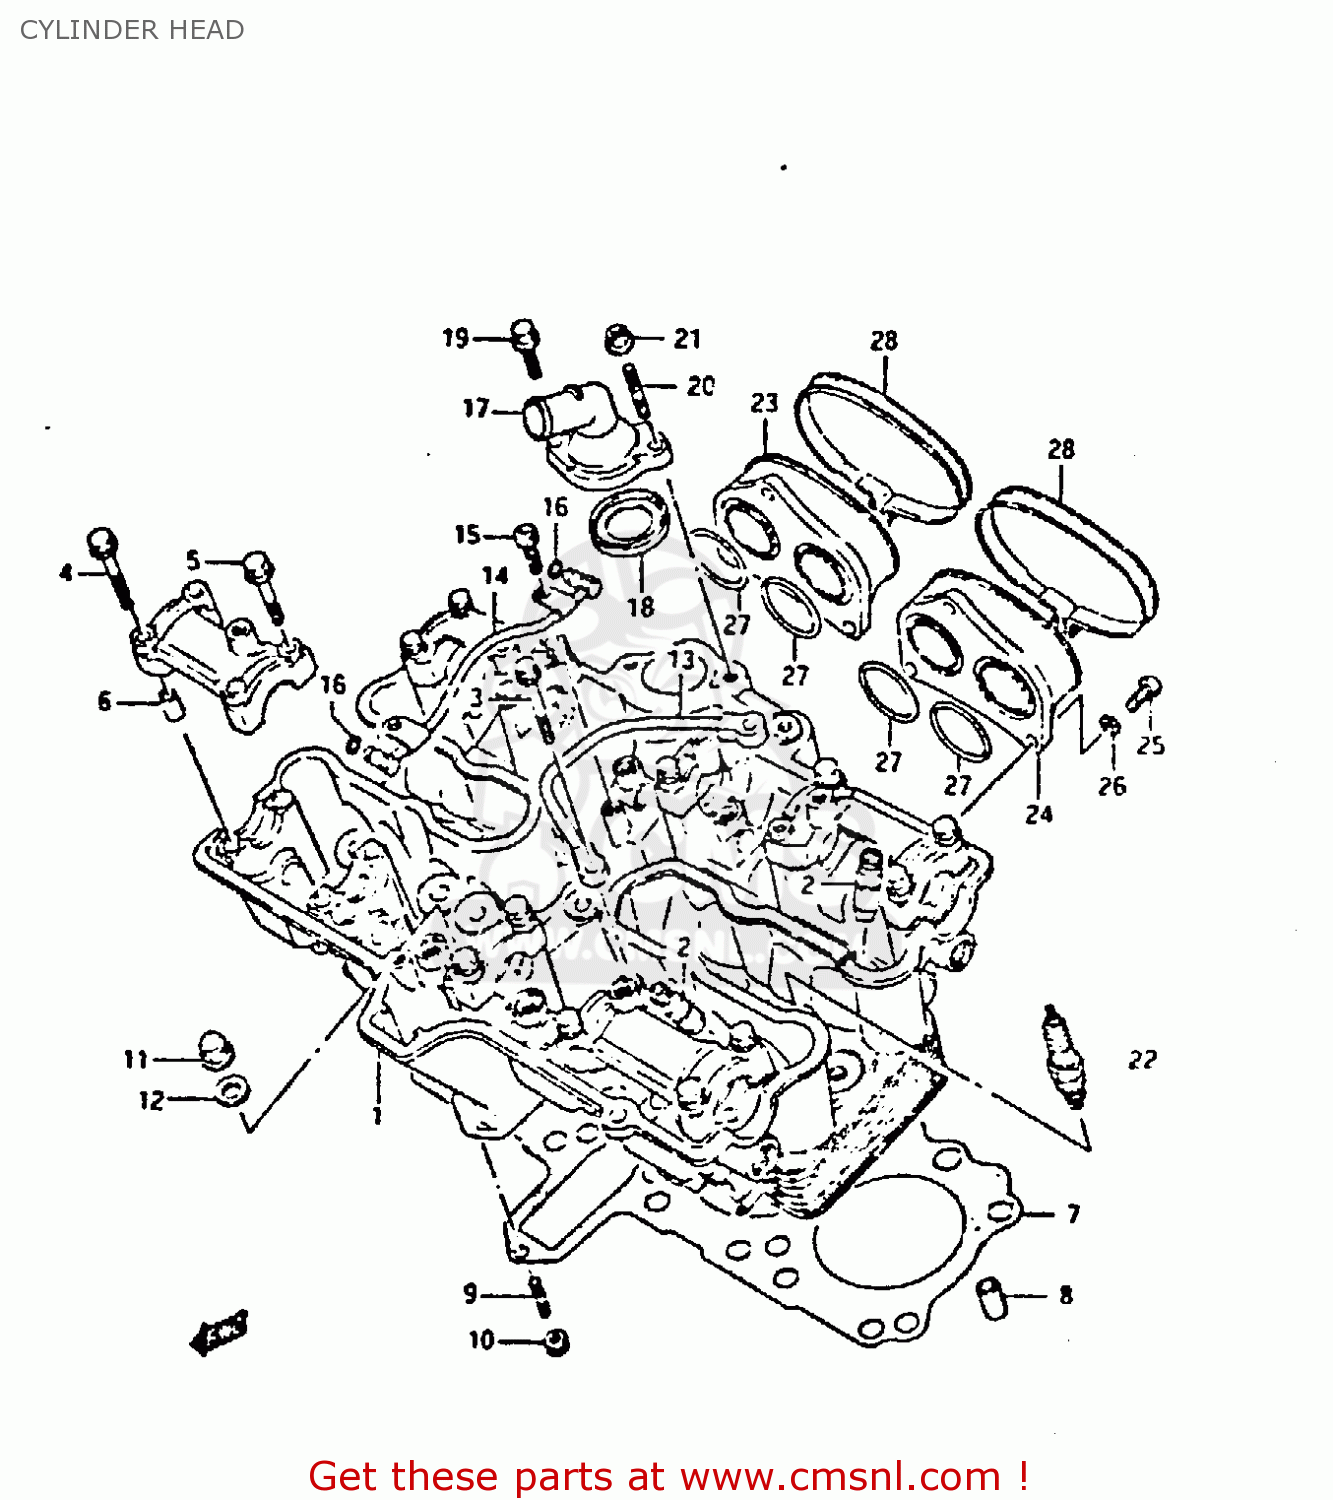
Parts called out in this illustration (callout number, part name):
1	KOP. CYLINDER
2	GUIDE,VALVE
3	BOLT
4	BOLT(6X39)
5	BOLT(6X35)
6	PIN(6.2X8X11)
7	GASKET,CYLINDER HEAD
8	PIN
9	STUD 6X16
10	NUT 6MM
11	NUT
12	GASKET(8.5X17X2.3) (NAS)
13	PIPE,OIL CYLINDER HEAD,L
14	PIPE,OIL CYLINDER HEAD
15	BOLT,STRANGER
16	O RING(D:1.9,ID:4.8)
17	THERMOSTAT COVER
18	SEAL,THERMOSTAT COVER
19	BOLT
20	BOLT.STUD
21	NUT 6MM
22	BOUGIE U24FS-C
23	INLAATRUBBER. R
24	INLAATRUBBER. L
25	SCREW
26	WASHER,LOCK
27	O RING(D:2.4,ID:31.7)
28	CLAMP
